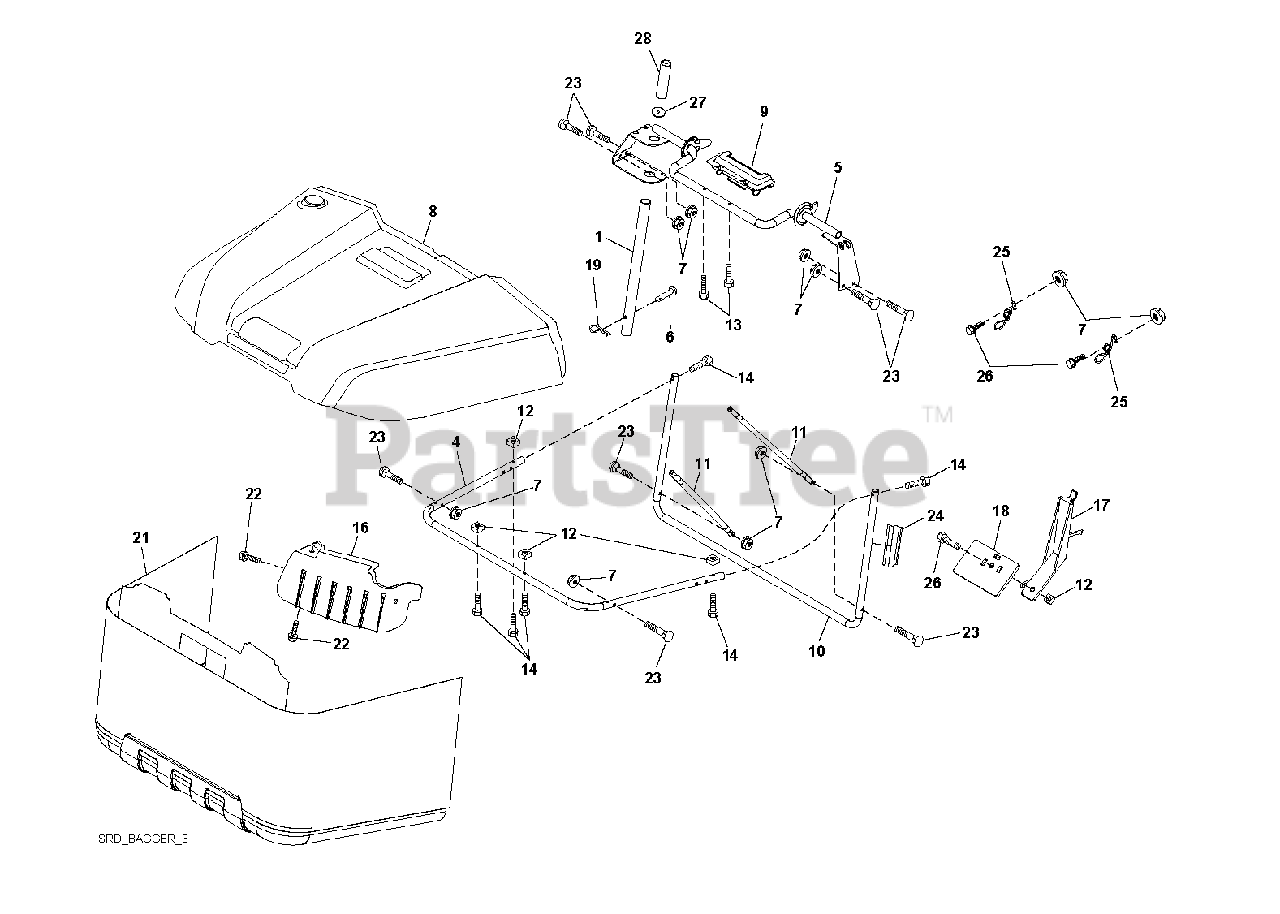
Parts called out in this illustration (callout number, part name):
1	TUBE HANDLE
6	RIVET,DRILLED
7	NUT T
19	RETAINER-SPRNG RB
22	SCREW.HI-LO.CONSOLE
26	SCREW HEX CRT
28	GRIP.HANDLE.BLACK
